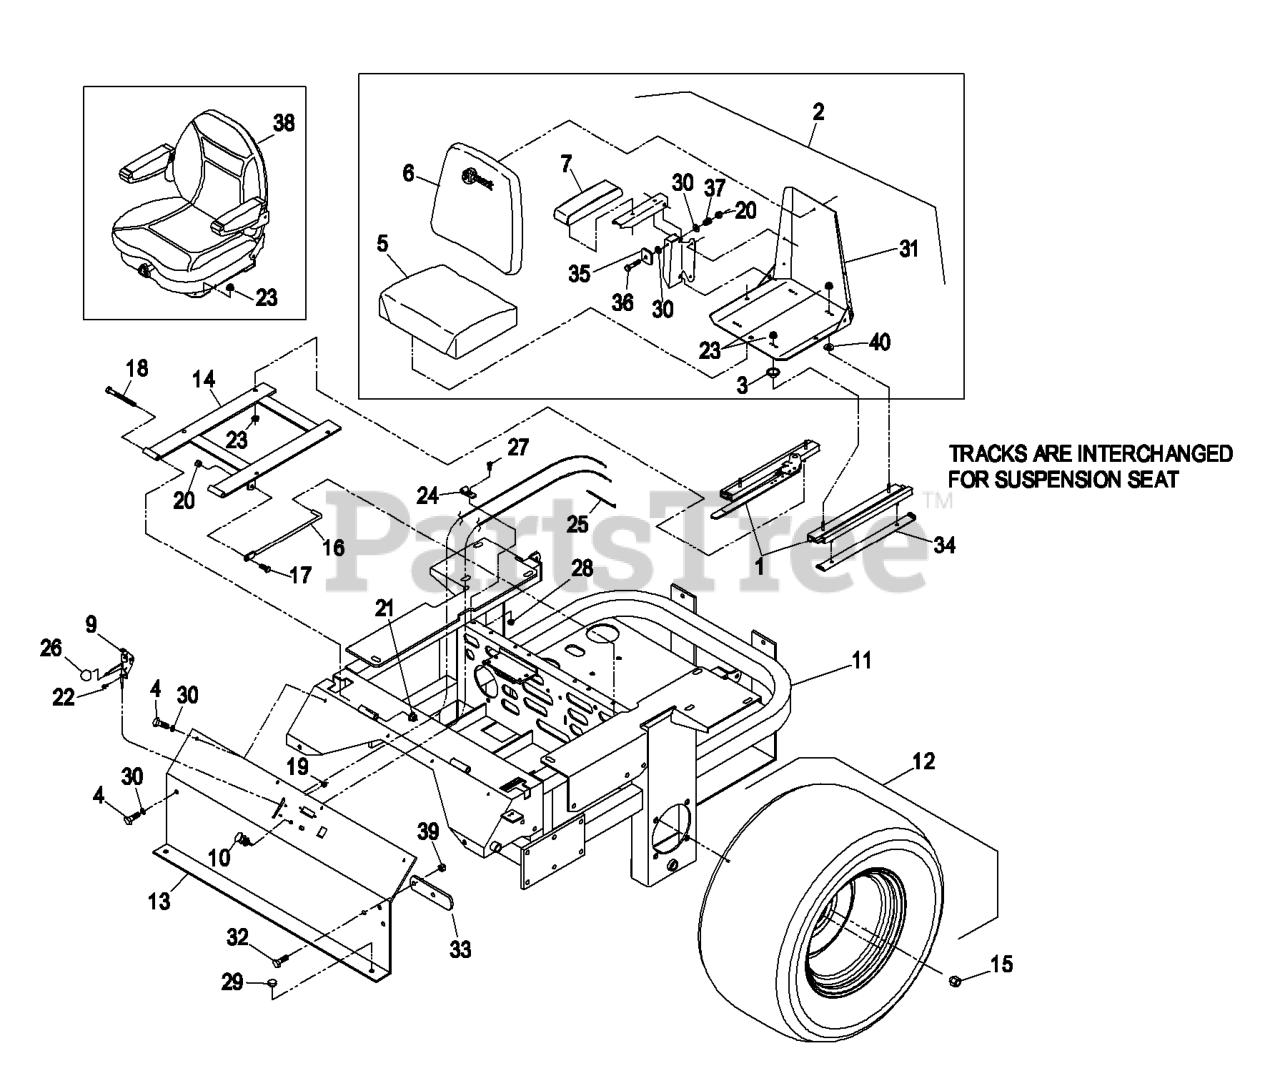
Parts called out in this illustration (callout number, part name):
1	TRACK-SEAT
3	SPACER-TRACK
4	SCREW-HH
7	CUSHION,ARMREST RH
9	THROTTLE CABLE ASM
10	CONTROL-CHOKE
13	ASM,CONSOLE W/DECALS LZ
15	NUT-LUG
16	ROD-HOLDUP, SEAT
17	SCREW-HH
18	SCREW-HH
19	NUT-LOCK, NI
20	NUT-LOCK, NI
21	NUT-LOCK, NI
22	BOLT-CARR
24	CLIP-LOOM
25	TIE-PLASTIC
26	KNOB-BALL
27	SCREW-HH
30	WASHER-PLAIN
31	FRAME-SEAT
32	SCREW-HH
33	STOP-BRAKE, PARK
34	STOP-SEAT
35	TAB,ARMREST ADJUSTMENT
36	SCREW-HH
37	SPRING-TANK, FUEL
39	NUT-HHF, WHIZ
40	WASHER-FLAT
